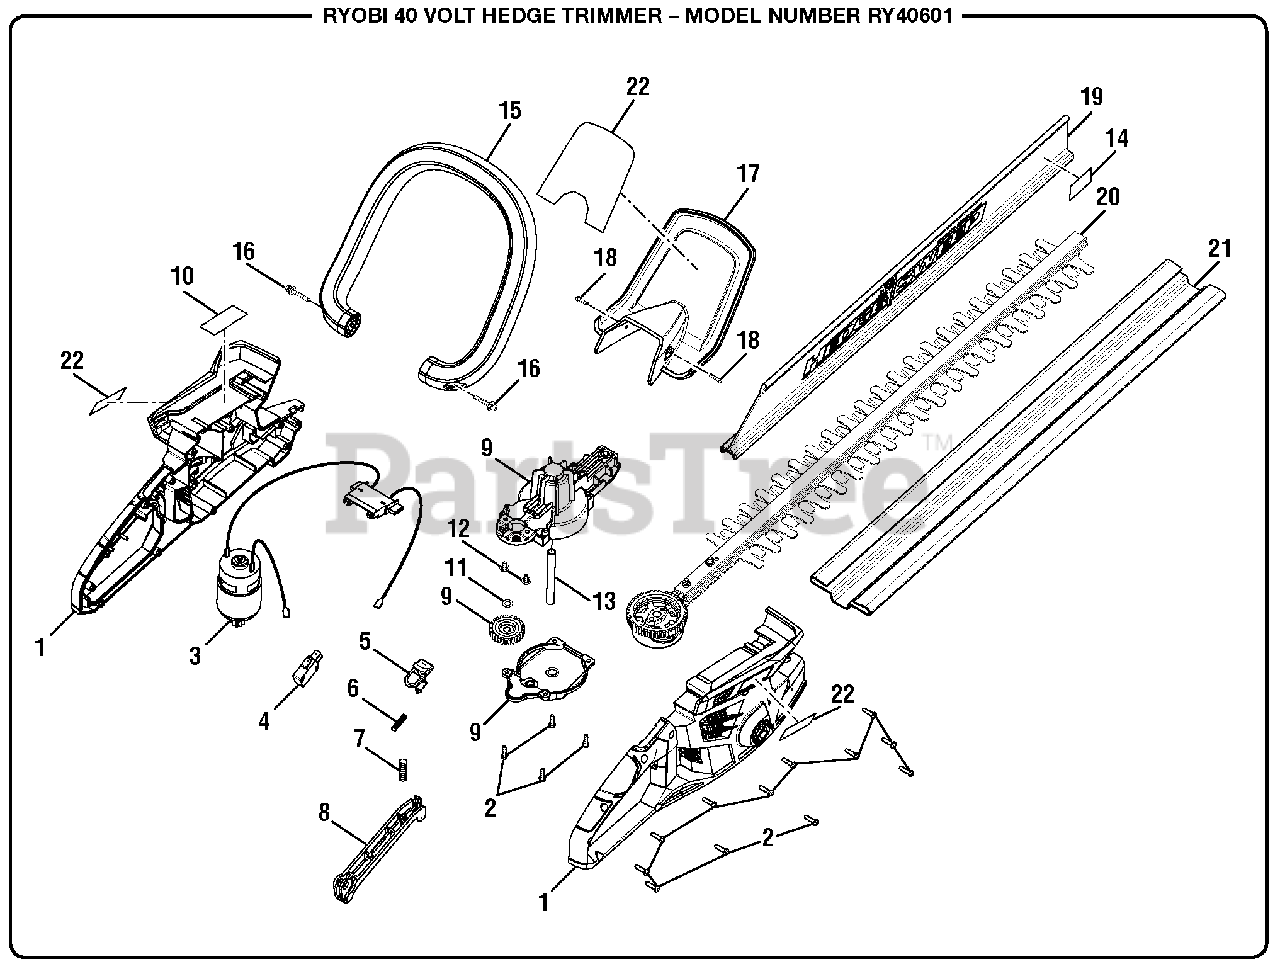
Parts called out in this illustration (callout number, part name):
1	Housing Assembly
2	Screw (M4 x 14 mm)
3	Motor and Contact Plate Assembly
4	Switch Assembly
5	Lock Off Button
6	Compression Spring
7	Compression Spring
9	Gear, Gear Case and Gear Cover Assembly
10	Data Label
11	Washer (ID6.2 x OD11 x 0.3t)
12	Screw (M4 x 12 mm)
13	Output Shaft
14	Warning Label
15	Front Handle Assembly
16	Screw w/Washer (M3 x 12 mm)
17	Safety Guard
18	Screw (M3 x 12 mm)
19	Hedge Sweep
20	Blade Assembly
22	Icon Label
23	Logo Label
